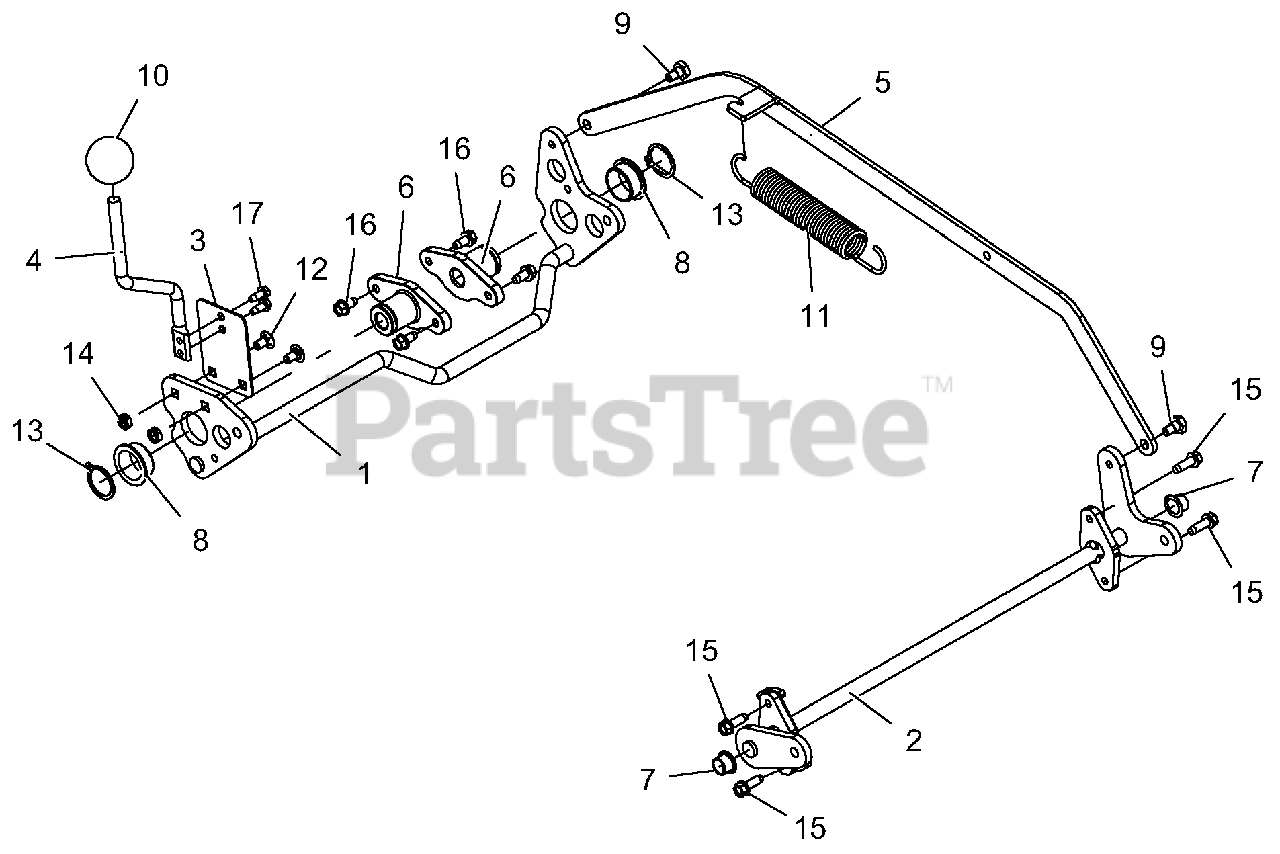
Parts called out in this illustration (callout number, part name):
1	WMT,RR AXL(SEE BULLETIN B2119)
2	WMT, LM FRONT AXLE
3	PLATE, HOC SPRING
4	LEVER, HOC ADJUSTMENT
5	LINK, HOC CONNECT
6	HUB, LM REAR AXLE
7	BUSHING, POLYLINER-.50 SPLIT
8	BSHG-FLG 1.0X1.125X.50X1.375 R
9	BOLT, SHLDR .320X.210X.25-20
10	KNOB,BALL -BLACK 1.47" .375-16
11	SG-TENS .121X1.00X6.5 WLD 12
12	@BLT-RDHDSQNK .25-20X.50 G5YZ
13	RG-RTNG-EXT 1.00X.042
14	NUT-LK-CTR JAM .25-20 YWZC
15	SCR-TAP-PM .25-20X.75 TR YWZ
16	SCR-TAP .25-20X.50 HWH TR YWZ
17	@SCR-TAP 12-24X.50 HWH TR YWZC
